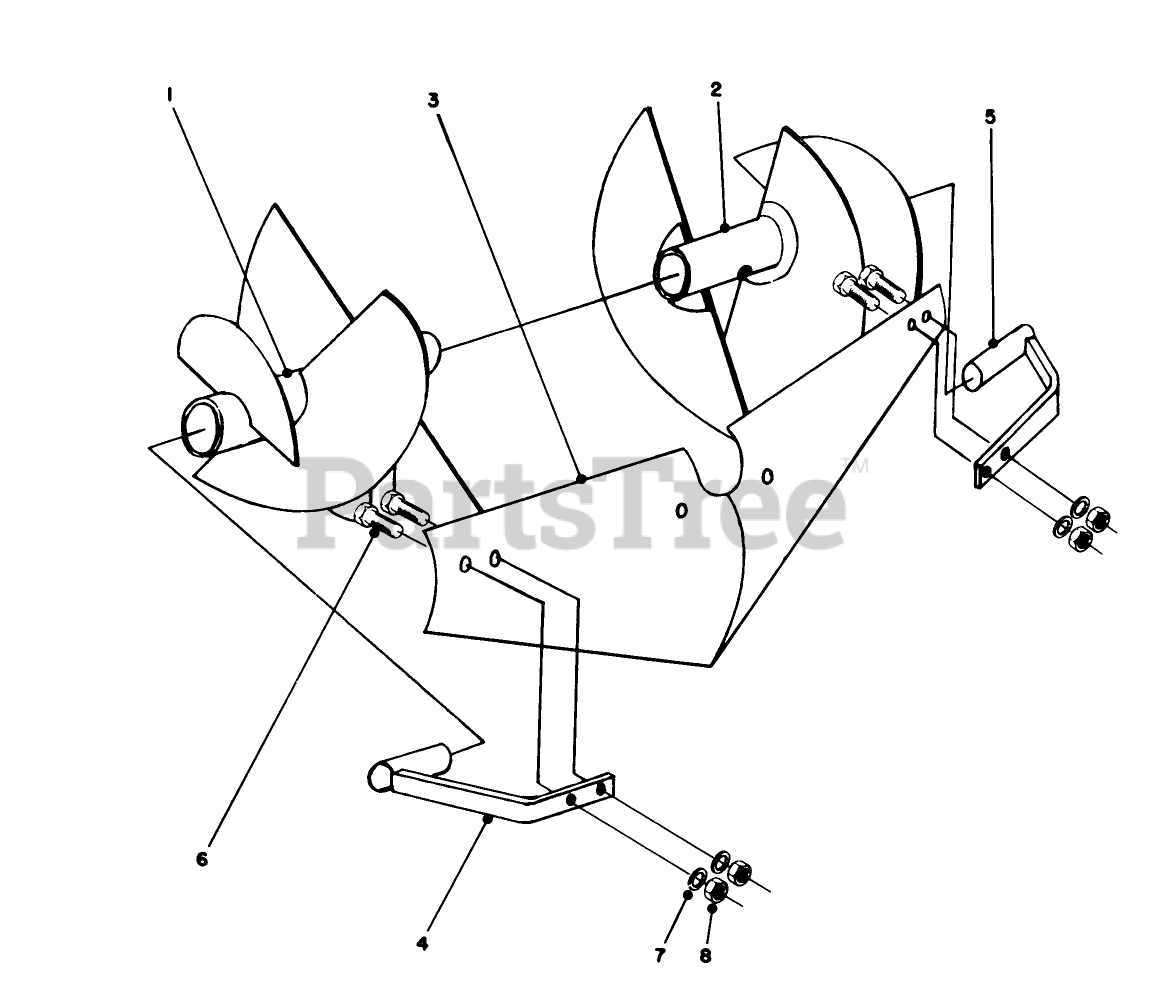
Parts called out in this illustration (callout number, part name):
1	Cultivator Blade L.H.
2	Cultivator Blade R.H.
3	Bedder Plate
4	Bracket L.H.
5	Bedder Bracket R.H.
